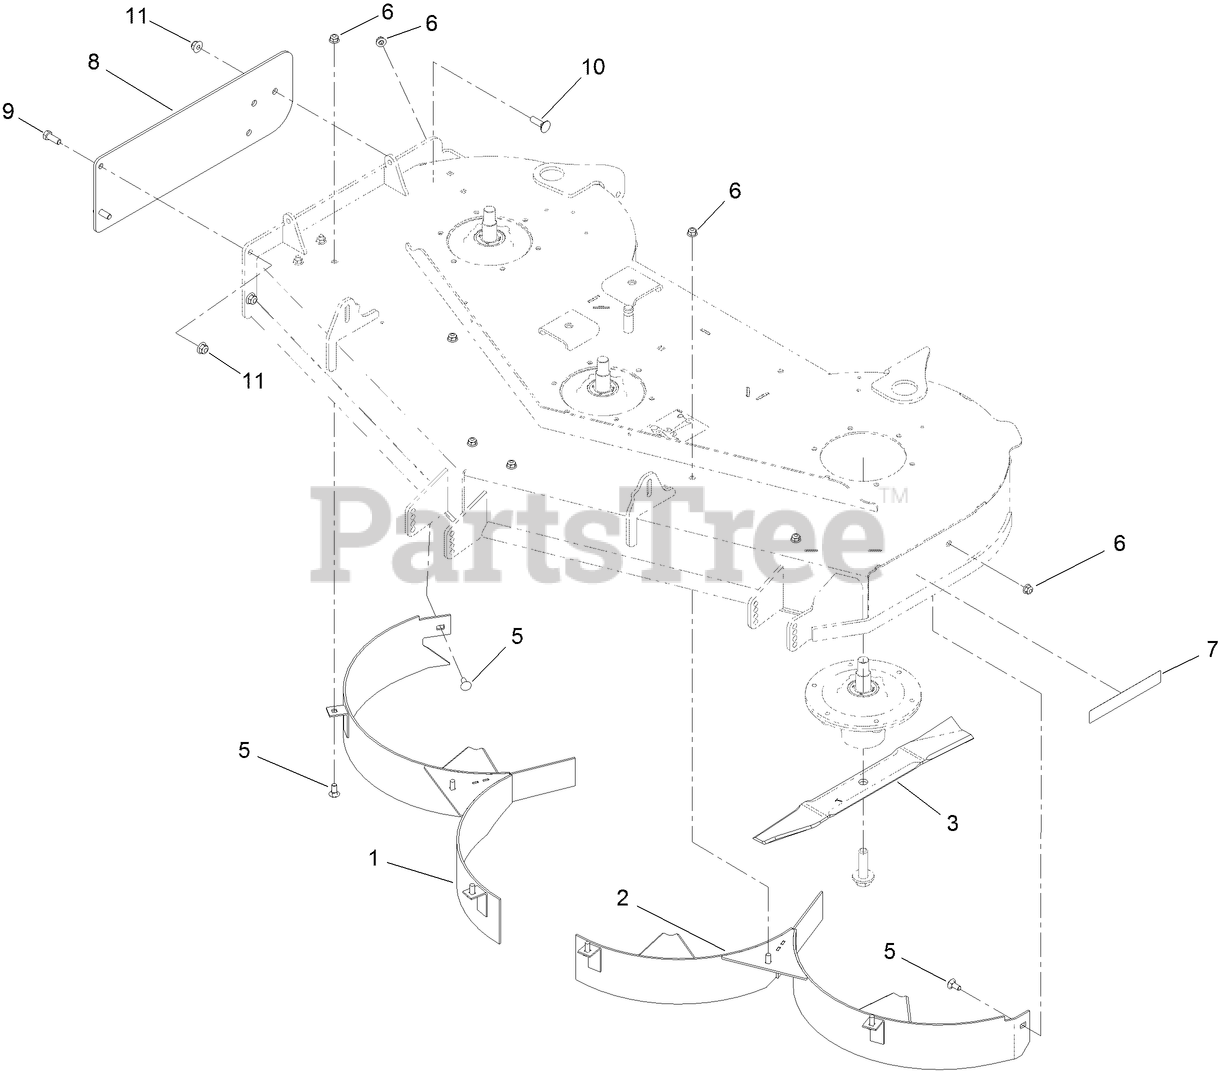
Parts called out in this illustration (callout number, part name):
1	BAFFLE-RECYCLER
2	BAFFLE-RECYCLER, LH
3	BLADE - MULCH, 18.75 IN
5	BOLT-CARR
6	NUT-HF, NI
7	DECAL-RECYCLER
8	PLATE-DISCHARGE, COVER
9	SCREW-HH
10	BOLT-CARR
11	NUT-HF, NI
